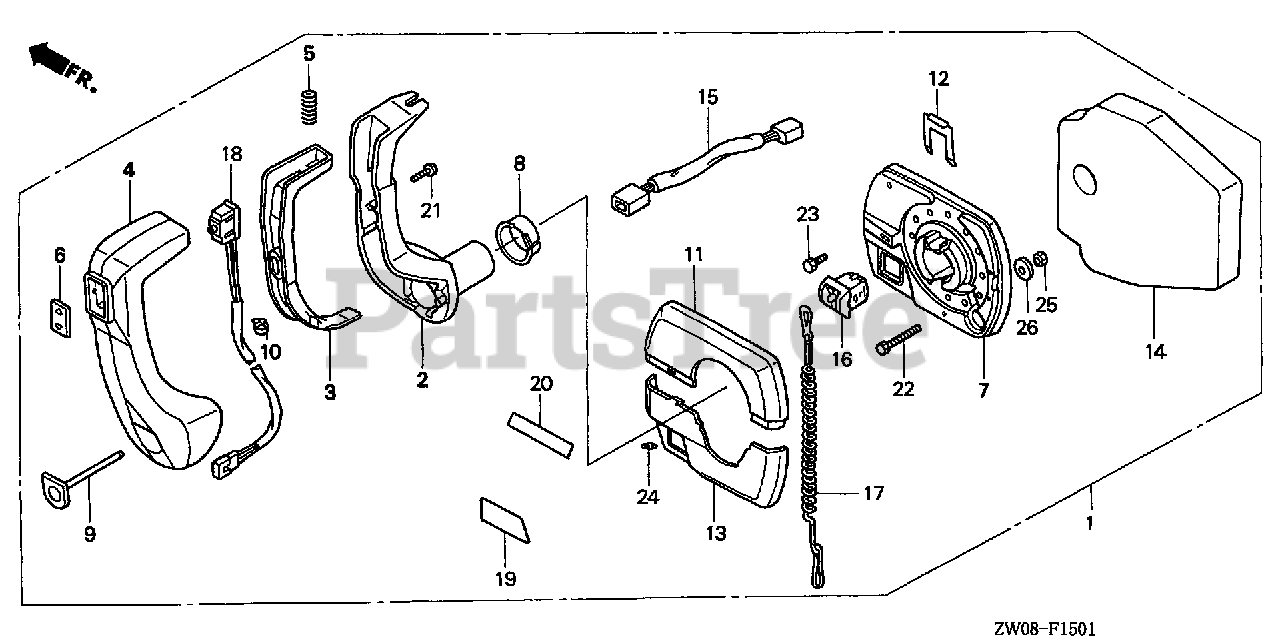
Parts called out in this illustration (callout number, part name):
1	BOX ASSY., REMOTE CONTROL (PANEL MOUNT) (NA USE ALT:06240-ZW7-U00)
2	HANDLE, REMOTE CONTROL
3	LEVER, HANDLE LOCK
4	GRIP, REMOTE CONTROL HANDLE
5	SPRING, REMOTE CONTROL HANDLE
6	COVER, GRIP
7	HOUSING ASSY., REMOTE CONTROL BOX (A)
8	BUSHING Use up to Frame SN 4000953.
9	BUTTON, THROTTLE
10	BAND B, CABLE Use up to Frame SN 4000953.
11	HOUSING ASSY., REMOTE CONTROL BOX (B)
12	RETAINER
13	HOUSING, REMOTE CONTROL BOX (C)
14	HOUSING ASSY. (INNER) (PANEL MOUNT)
15	HARNESS ASSY., POWER TRIM-TILT Use from Frame SN 4000954.
16	SWITCH ASSY., EMERGENCY STOP
17	WIRE, EMERGENCY
18	SWITCH ASSY., POWER TRIM-TILT (A) Use up to Frame SN 4000953.
19	MARK, REMOTE CONTROL (A)(PANEL)
20	MARK, REMOTE CONTROL (B)(FOR STARBOARD)
20	MARK, REMOTE CONTROL (C)(FOR PORT)
21	SCREW A (NOT AVAILABLE)
22	SCREW B
23	SCREW C
24	SCREW SET (1/4-20X16") Use up to Frame SN 4000953.
25	NUT (1/4X20)
26	WASHER
